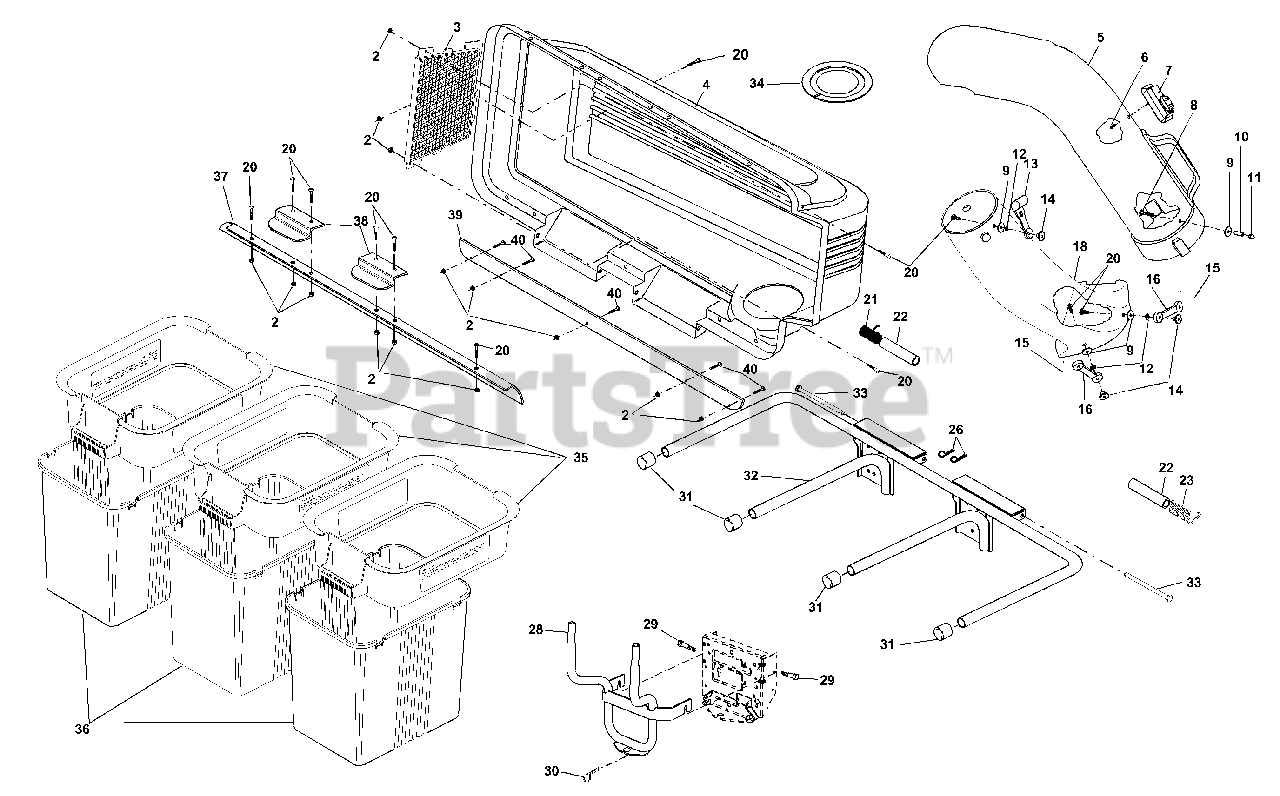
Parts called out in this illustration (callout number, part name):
2	Nut, Crownlock #10-24
3	Screen, Cover
4	Cover
5	Chute, Upper
6	Screw, Special #10-14x1/2
7	Dump Bag Indicator
8	Screw, #10-24 x 1-1/8
9	Washer 3/16 x 3/4 x 16 Ga.
10	Spacer, Split
11	Nut, Acorn #10-24
12	Washer, lock
13	Latch, Chute
14	Nut, Weld
15	Latch, Hook
16	Rubber, Latch
18	Chute, Lower
20	Screw #10-24 x 5/8
21	Spring, Cover L.H. (black)
22	Spacer, Cover
23	Spring, Cover R.H. (gray)
26	Spring, Retainer
28	Support Assembly
29	Shoulder Bolt, Self Tapping
30	Spring, Retainer
31	Plug, Tubing End
32	Bagger, Frame
33	Pin, Hinge
34	Gasket, Cover
35	Container, Top
36	Container, Bottom
37	Seal, Cover
38	Latch Handle, Cover
39	Strip, Reinforcement
40	Screw #10-24 x 1/2
